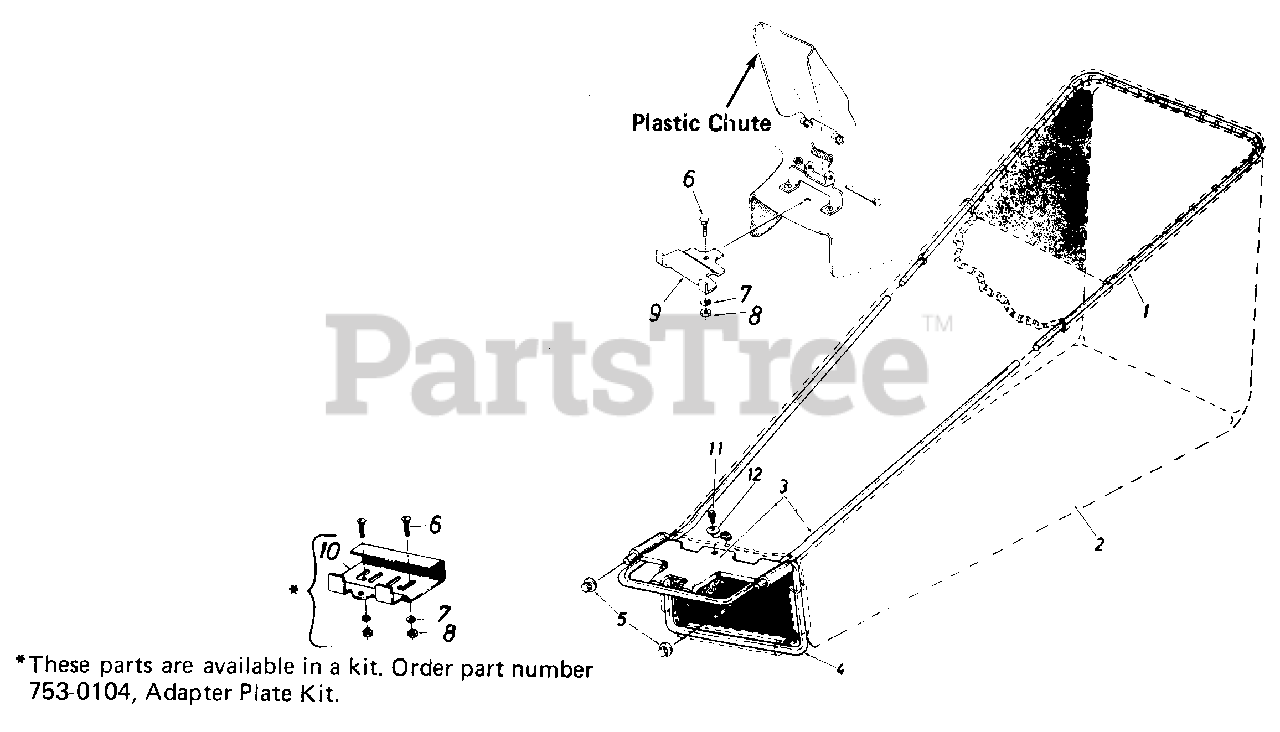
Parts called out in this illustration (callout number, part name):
2	Grass Catcher Bag
3	Frame-Lower
4	Lower Frame Rod
5	Push Cap
6	Carriage Bolt
7	LockWasher1/4" I.D.
8	Hex Nut 1/4-20 Thd.
9	Adapter Plate
10	Adapter Plate
11	Self-Tap Scr. 1/4 x 1/2" Lg.
12	Bell-Wash. 1/4" I.D.
